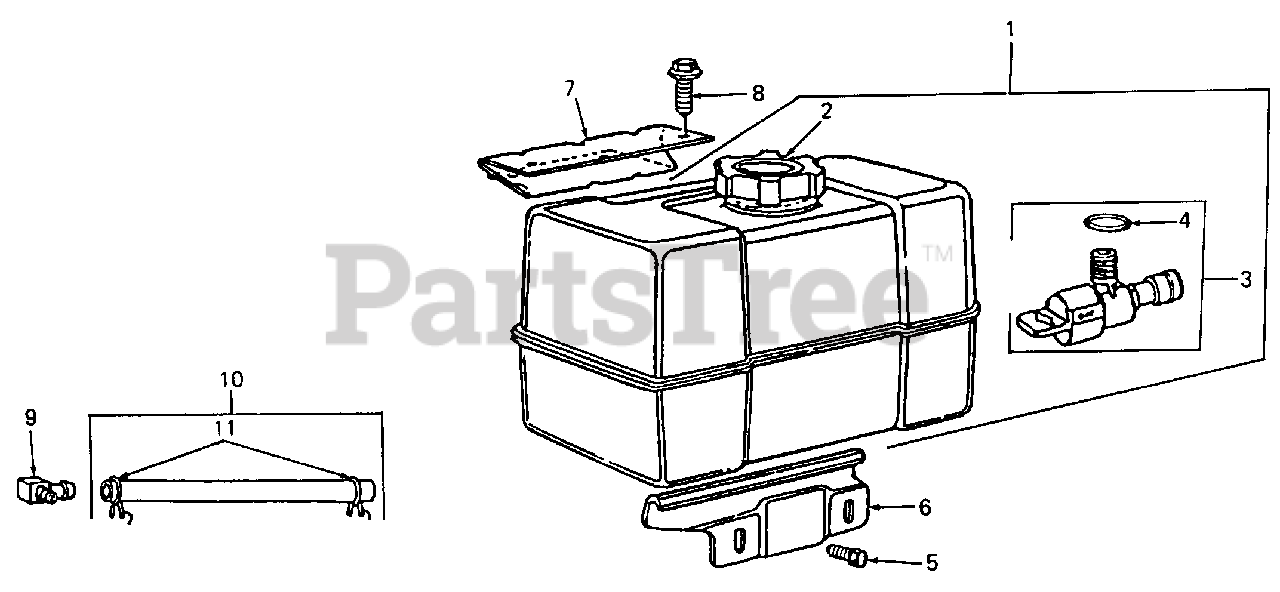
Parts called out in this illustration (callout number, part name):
1	Fuel Tank Assy
2	Cap, Fuel Tank
3	Valve Assy, Fuel Shutoff
5	Screw, Sem
6	Bracket, Lower, Fuel Tank
7	Bracket, Upper, Fuel Tank
8	Screw, Tank Mounting
9	Connector, Fuel Pipe
10	Pipe, Fuel -23" Lg
11	Clamp, Fuel Pipe
